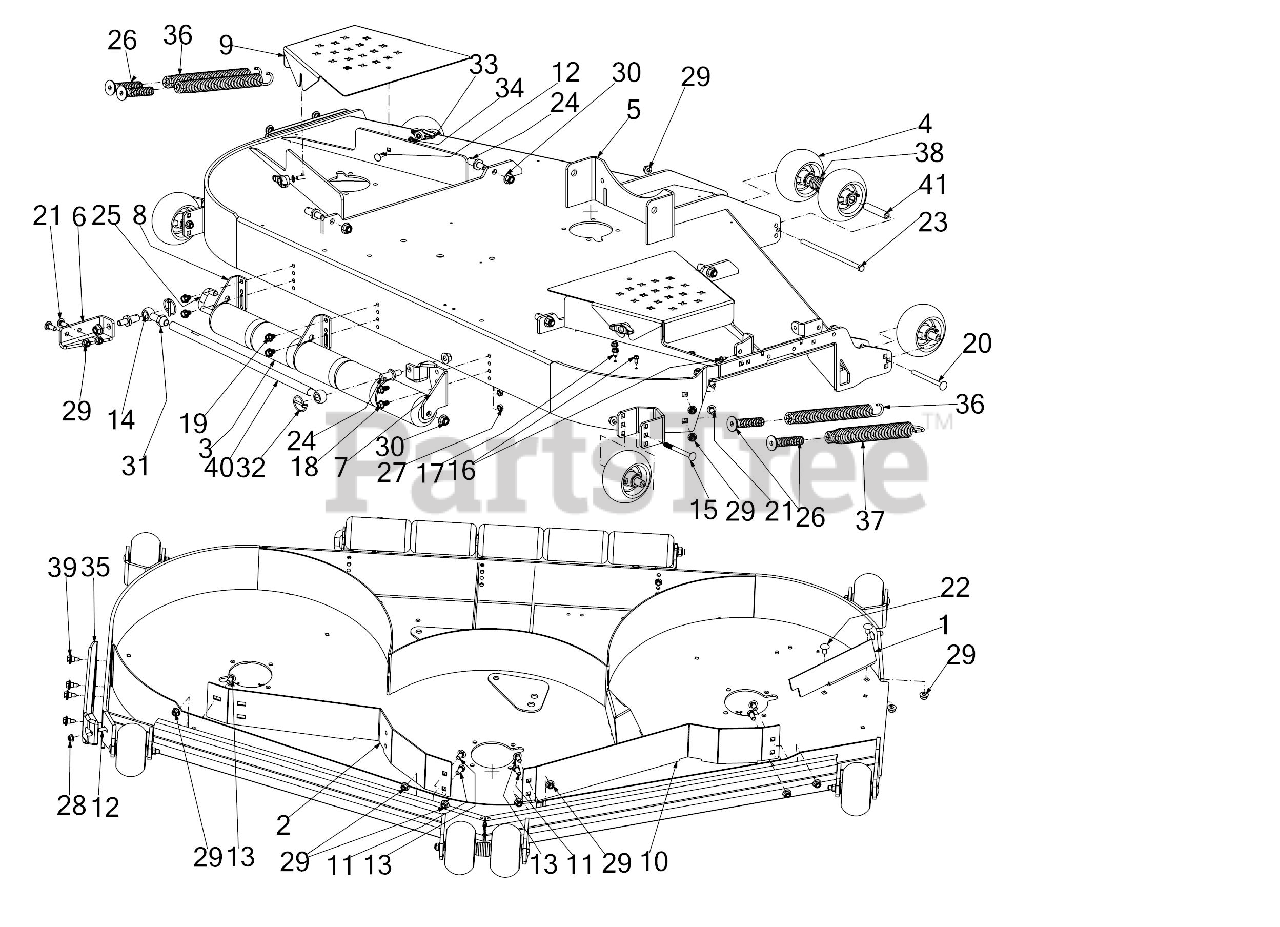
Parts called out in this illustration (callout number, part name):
3	ROLLER ASSEMBLY
4	WHEEL ASSEMBLY 5"
5	DECK SHELL
6	STABILIZER MOUNTING BRACKET
7	REAR ROLLER/STABILIZER BRACKET
8	REAR MOUNT BRACKET
11	HEX SCREW 3/8-16 x .75
12	CARRIAGE BOLT 5/16-18 x 1.00
13	CARRIAGE BOLT 3/8-16 x .750 GR5
14	BOLT 5/8-16 x 2.63
15	CARRIAGE BOLT 3/8-16 x 4.00 GR5
16	SCREW 1/4-20 X.500
17	SCREW 5/16-18 x .500
18	SCREW 3/8-16 x 3/4
19	SCREW 3/8-16 x .500
20	CARRIAGE BOLT 3/8-16 x 4.25 GR5
21	CARRIAGE BOLT 3/8-16 x 1.00 GR5
22	CARRIAGE BOLT 3/8-16 x .75
23	SCREW 3/8-16 x 8.5 GR5
25	REAR ROLLER PIN
26	SPRING INSERT SCREW
27	JAM LOCK NUT
28	FLANGE LOCK NUT 5/16-18
31	HEX NUT
33	WING KNOB 5/16-18
35	DECK SKID PLATE (LH)
36	EXTENTION SPRING 1.20 x 11.35
37	EXTENSION SPRING 1.44 OD X 11.36
38	FLAT WASHER
39	SHOULDER SCREW .43X.29X5/16-18 TT
41	WHEEL SPACER .38ID x 3.04LG
